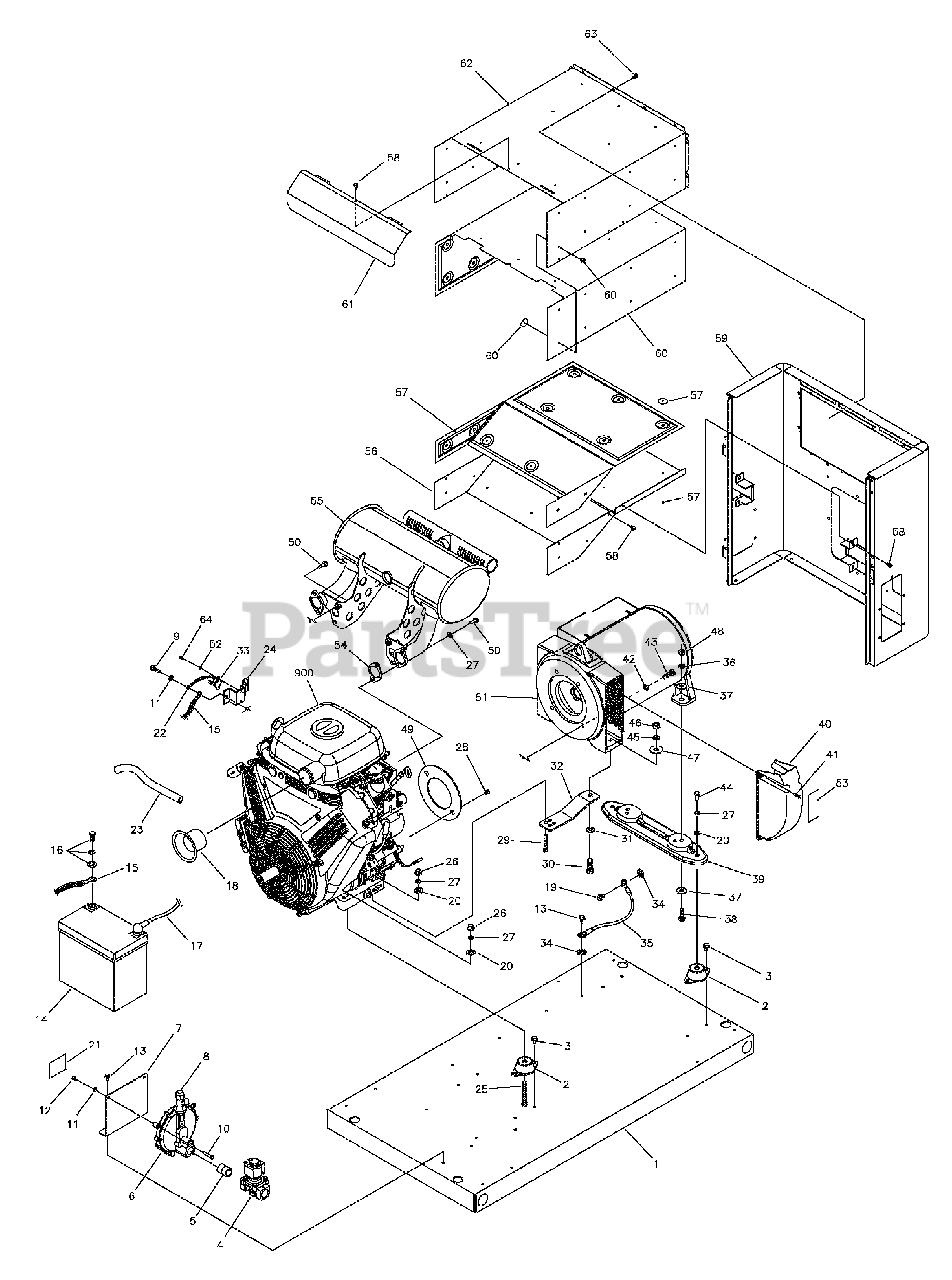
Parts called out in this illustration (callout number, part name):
1	BASE
2	MOUNT, Vibration
4	SOLENOID, Gas Fuel
6	REGULATOR, NG/LPG
7	BRACKET
9	*CAPSCREW, Hex Head, M6-1.0 x 16
10	*CAPSCREW, Hex Head, M6-1.0 x 30
11	*WASHER, Lock, 1/4
12	*NUT, M6-1.0
13	BOLT
16	KIT, Hardware, Battery
19	*CAPSCREW, Hex Head, M6-1.0 x 12
20	*WASHER, Flat, 5/16-M8
23	HOSE, Oil Drain
24	PLATE, Temp Switch
25	*CAPSCREW, Hex Head, 5/16-18 x 2-1/2
26	*NUT, 5/16-18
27	*WASHER, Lock, 5/16-M8
28	*CAPSCREW, Hex Head, 5/16-24 x 3/4
29	*CAPSCREW, Hex Head, 5/16-18 x 2
30	*CAPSCREW, Hex Head, M12-1.75 x 35
31	*WASHER, M12
32	SUPPORT, Engine
33	SWITCH, Temp
34	*WASHER, Shakeproof, M6-1/4
36	*WASHER, Lock, M10
37	*WASHER, Flat, M10
38	*CAPSCREW, Hex Head, M10-1.5 x 30
39	SUPPORT, Alternator
41	*SCREW, Phillips Head, M5-0.8 x 20
42	*WASHER, Lock, 3/8
43	*CAPSCREW, 3/8-16 x 1-1/4
44	*CAPSCREW, Hex Head, 5/16-18 x 3/4
45	*WASHER, Lock, M12
46	*NUT, Hex, M12
47	*WASHER, Flat, M12
48	*NUT, M10
50	SCREW
51	ALTERNATOR
52	*WASHER, Lock, #4
59	BULKHEAD, Alternator
62	BOX, Muffler, Top
64	*SCREW, Phillips Head, 4-40 x 0.19
900	**ENGINE
